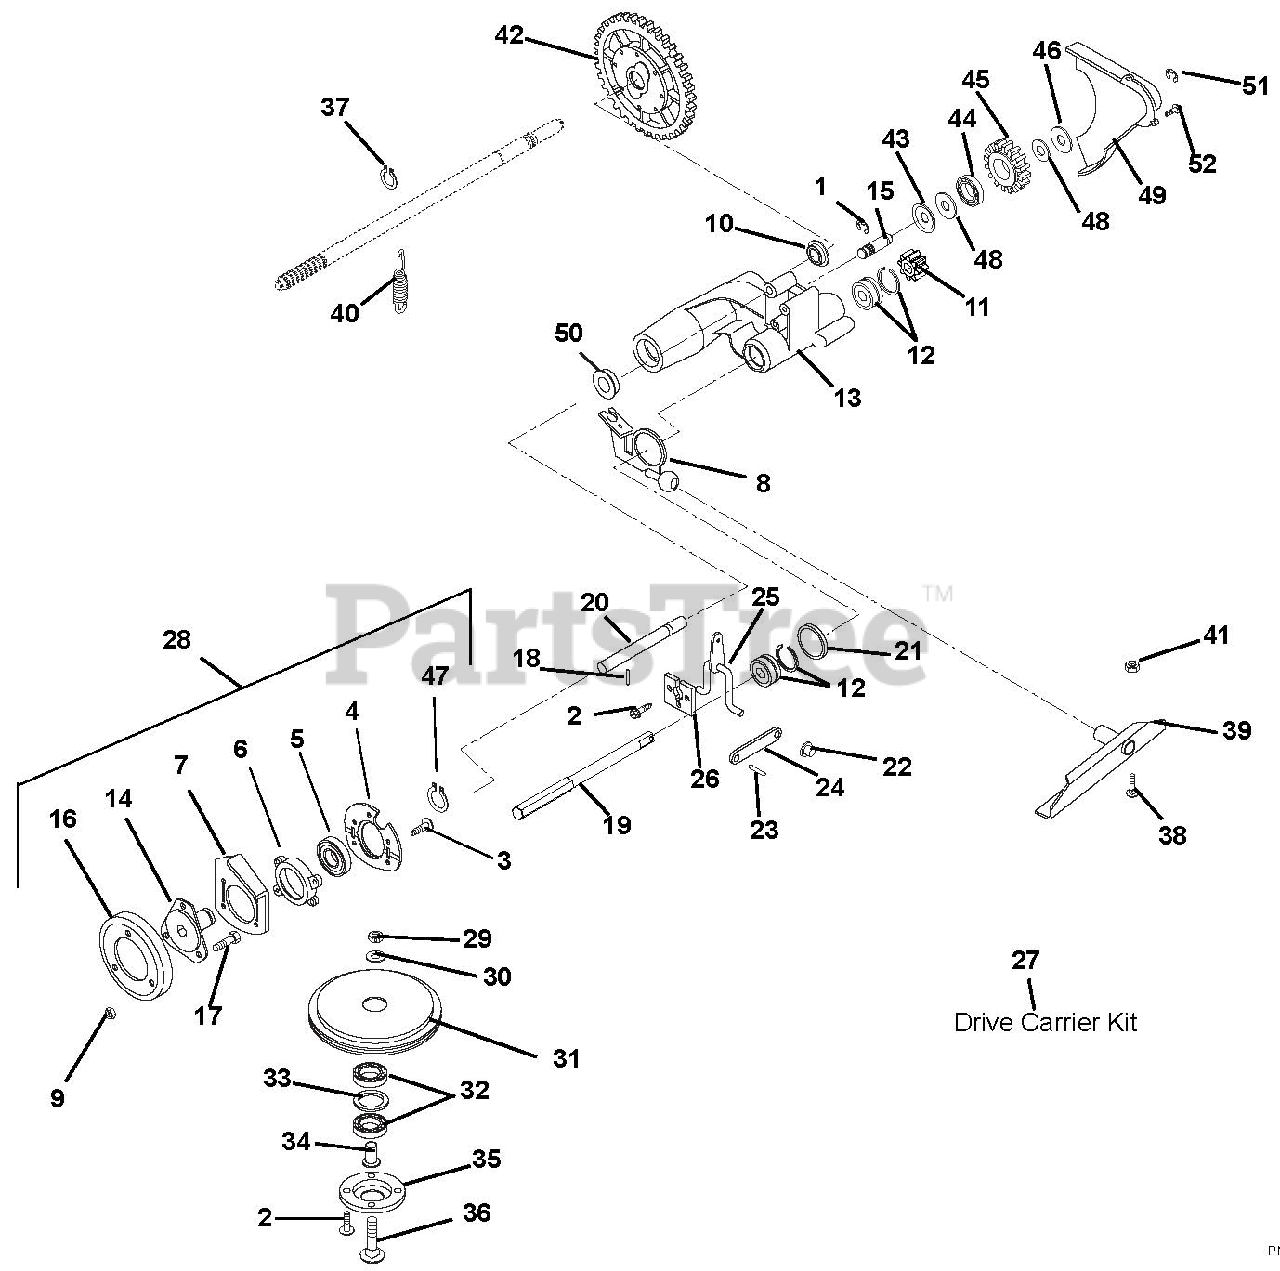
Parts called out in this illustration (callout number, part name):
1	RG-RTNG-EXT .438X.035
2	@SCR-TAP 12-24X.50 HWH TR YWZC
3	SCR-TAP 5HX-0.8X16MM H-FL-YWZC
4	BEARING RETAINER
5	BRG-BALL 1.0X2.0X.56 (1641)
6	BEARING RETAINER
7	PLATE, BEARING
8	ACTUATOR, WBLM DRIVE
9	@NUT-LK-CTR .25-20 YWZC
10	BRG-BALL .625X1.378X.44
11	PINION, D-SHAFT
12	BRG-BALL .50X1.38X.438 SEALED
13	DRIVE CARRIER
14	FRICTION WHEEL HUB
15	IDLER SHAFT
16	DISC, FRICTION - 730 MAT'L
17	@BLT-HEX .25-20X.50 GR5 YWZC
18	PIN-ROLL .188X.88
19	SHAFT, FRICTION DISK
20	ROD - GUIDE
21	WSHR-FL-STL 1.390X2.00X.020 PL
22	PUSH NUT, .25
23	PIN-ROLL .125X.50
24	SHIFT LINK
25	SHIFT ARM WELDMENT
26	RETAINER PLATE
27	KIT, LM DRIVE CARRIER
28	KIT, COM. DRIVE CONVERSION
29	@NUT-LK-CTR .31-18 YWZC
30	WSHR-FL-STL .328X.87X.179 YWZC
31	FRICTION SHEAVE
32	BRG-BALL .625X1.375X.43
33	WSHR-FL-STL 1.062X1.344X.032PL
34	SPINDLE - BEARING
35	RETAINER - BEARING
36	@BLT-RDHDSQNK .31-18X1.75 G5YZ
37	RG-RTNG-EXT .579X.035
38	@BLT-RHDSSQNK .31-18X.62 G5YZ
39	PIVOT, CHANNEL WELDMENT
40	SG-TENS .051X.60X2.25 WLD 7.0
41	@NUT-LK-TOP-FLG .31-18 YWZC
42	DIFFERENTIAL ASSEMBLY
43	RETAINER
44	BRG-BALL .500X1.38X.437
45	IDLER GEAR
46	WSHR-FL-STL.531X1.00X.063 YWZC
47	RG-RTNG-EXT 1.00X.042
48	WSHR-FL-STL .52X.827X.062 YWZC
49	COVER, GEAR
50	BRG-BALL .625X1.383X.50
51	RG-RTNG-EXT .438X.035
52	@SCR-TAP 12-24X.50 HWH TR YWZC
